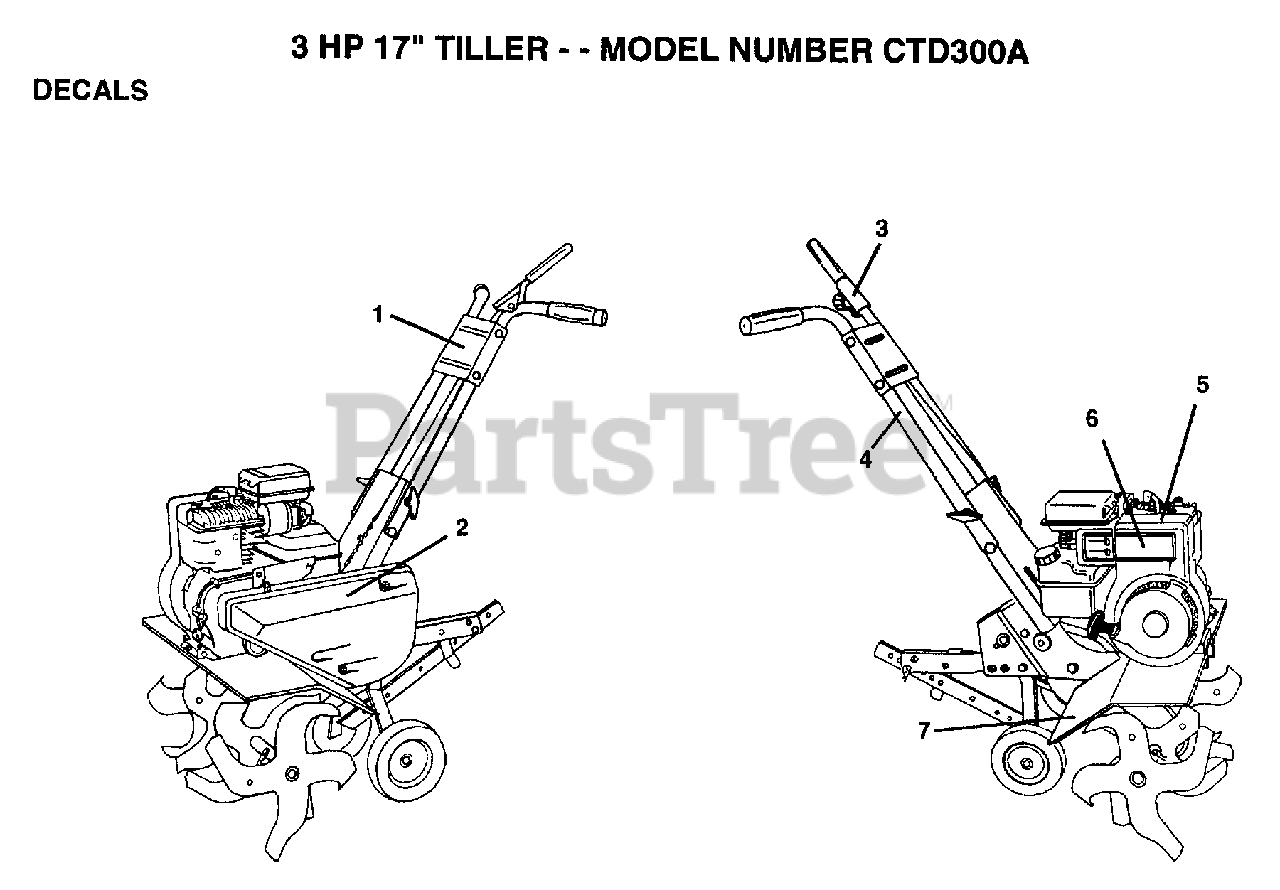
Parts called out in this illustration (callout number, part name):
1	DECAL PNL CNTL
2	DECAL.GUARD.BELT
3	DECAL TI
4	DECAL TI
6	"DECAL,ENG HP"
7	DECAL TI
